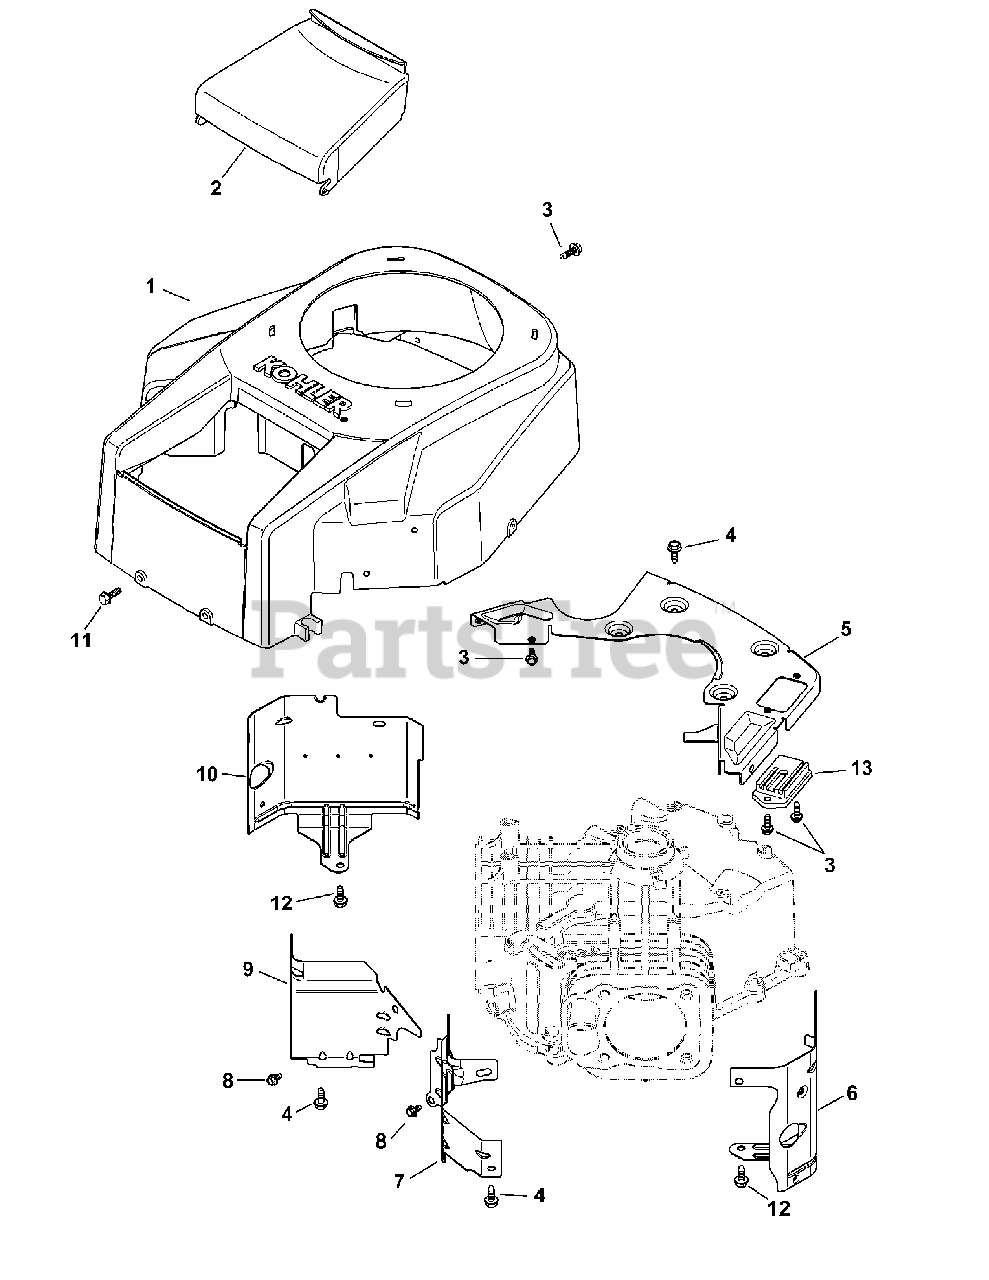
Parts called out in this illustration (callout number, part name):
1	Blower Housing Kit
2	Air Cleaner Cover
3	Flange Screw, M5 x .8 x 16
4	Flange Screw, M6 x 1.0 x 16
5	Backing Plate Kit
6	Cylinder Barrel Baffle, #2 Side
7	Valley Baffle, #2 Cylinder
8	Flange Screw, M5 x .8 x 10
9	Valley Baffle, #1 Cylinder
10	Cylinder Barrel Baffle, #1 Side
11	Screw, M6 x 1.7 x 18
12	Flange Screw, M6 x 1.0 x 10
13	Regulator/Rectifier
